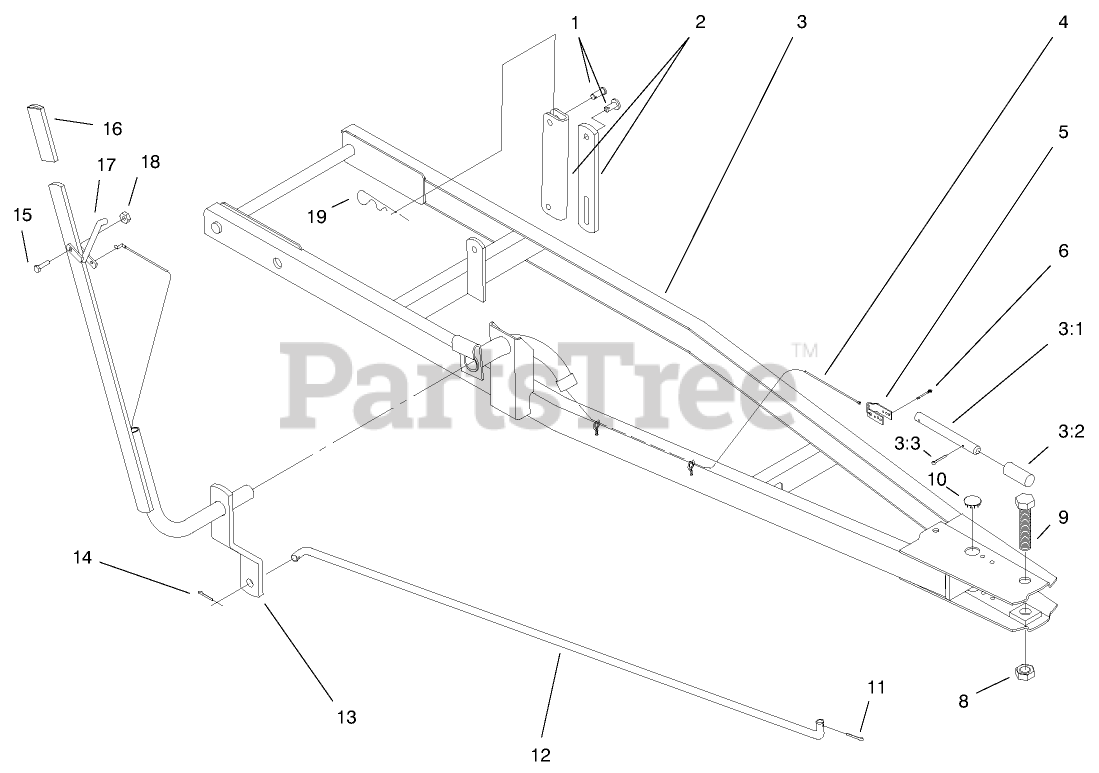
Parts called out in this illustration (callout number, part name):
1	PIN-CLEVIS
1	PIN-WELD
2	LINK - LIFT
3	WA - FRAME PAINT RED
3:1	PIN-INDEX
3:2	SPRING-COMPRESSION
3:3	PIN-COTTER
4	CABLE - INDEXING
5	BRACKET - CABLE END
6	PIN-COTTER
8	NUT-LOCK, NI
9	SCREW-HH
10	PLUG
11	PIN-COTTER
12	ROD - BLADE CONTROL
13	Lever Indexing
14	PIN-HAIR
15	SCREW-HH
16	GRIP
17	LEVER
18	NUT-LOCK
19	PIN-HAIR
